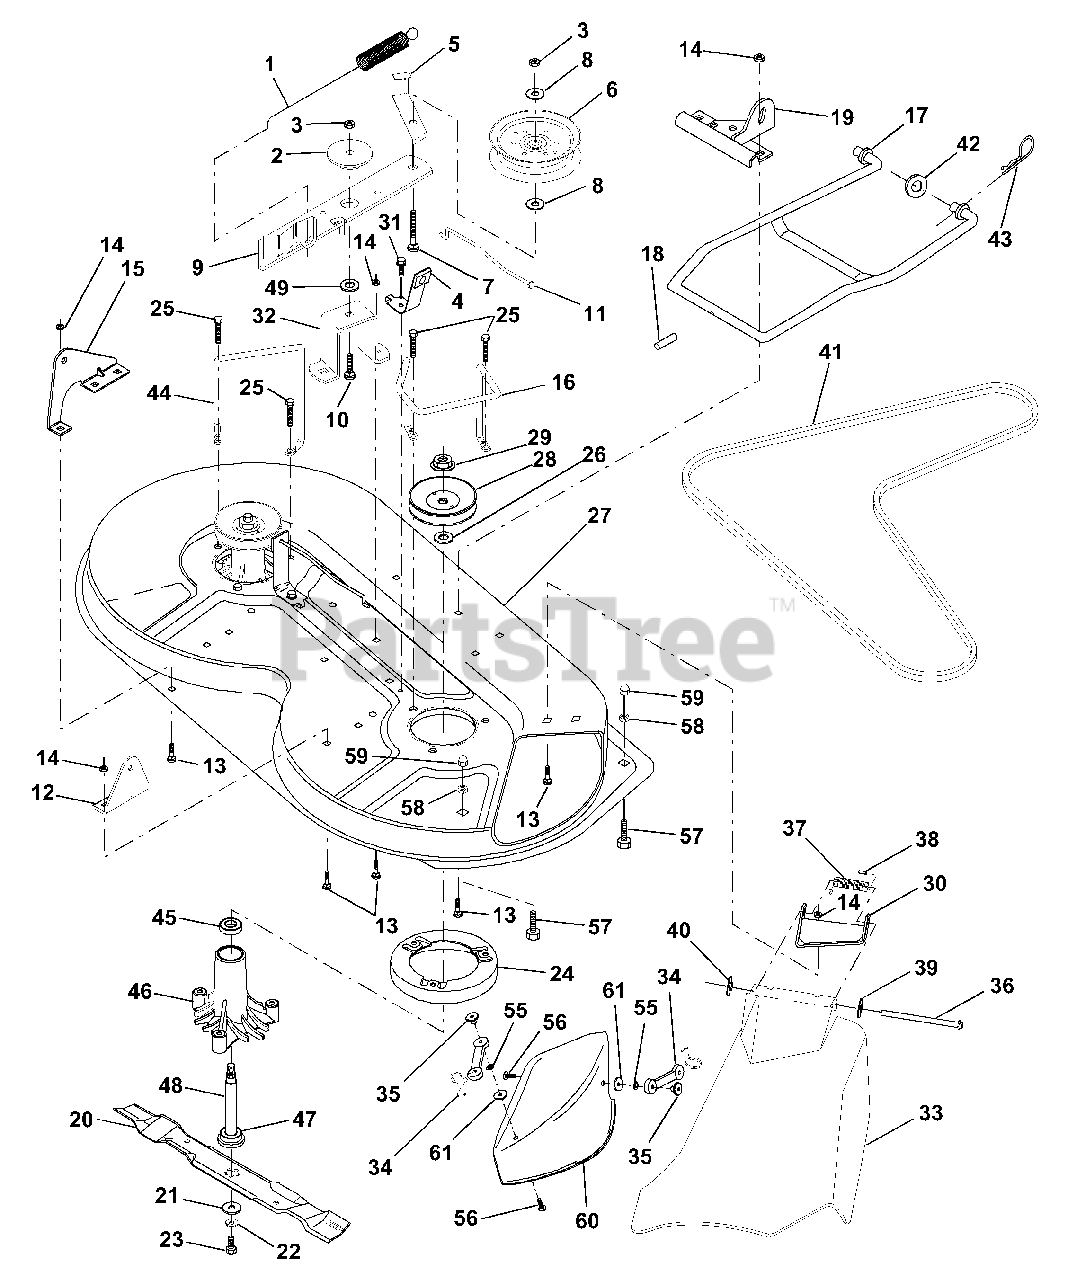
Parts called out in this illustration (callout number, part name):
1	Spring, Mower Clutch
2	Spacer, Retainer
3	Nut, Crownlock 3/8-16
4	Brake Asm.
5	Guide, Belt Idler
6	Pulley, Flat Idler
7	Bolt, Carr. 3/8-16 x 1-3/4 Gr. 5
8	Washer 13/21 x 7/8 x 10 Ga.
9	Arm Asm., Idler Mower
10	Bolt, Carriage 3/8-16 x 1-1/4
11	Rod, Brake
12	Bracket, Lift R. H. Rear
13	Bolt, Carriage 5/16-18 x 3/4
14	Nut, Crownlock 5/16-18
15	Bracket, Lift L. H. Rear
16	Keeper, R. H.
17	Link, Asm. Mower Stabilizer
18	Pin, Drive
19	Bracket, Asm. Front
20	Blade Mulching
21	Washer, Hard
22	Washer, Lock 3/8
23	Bolt 3/8-24 x 1-1/4 Gr. 8
24	Stripper
25	Screw Thdrol Hex Hd
26	Washer .150 Thk.
27	Deck Assembly
28	Pulley, Mandrel
29	Nut, Flangelock 9/16
30	Bracket, Asm. Deflector
31	Screw, Hex Wsh. Thdrol. 5/16-18 x 1/2
32	Arm, Support Idler Mower
33	Deflector
34	Latch Hook
35	Nut, Weld
36	Rod, Hinge
37	Spring, Torsion Deflector
38	Cap, Sleeve
39	Washer 11/32 x 5/8 x 16 Ga.
42	Washer 11/32 x 5/8 16 Ga.
43	Retainer, Spring
44	Keeper, L. H.
46	Housing Mandrel Vented
48	Shaft, Mandrel
49	Washer, Hardened
55	Washer, Lock #10
56	Screw
57	Bolt, Hex 5/16-18 x 1
58	Locknut 5/16-18
59	Acorn Nut 5/16-18
60	Mulcher Plate
61	Washer #10
